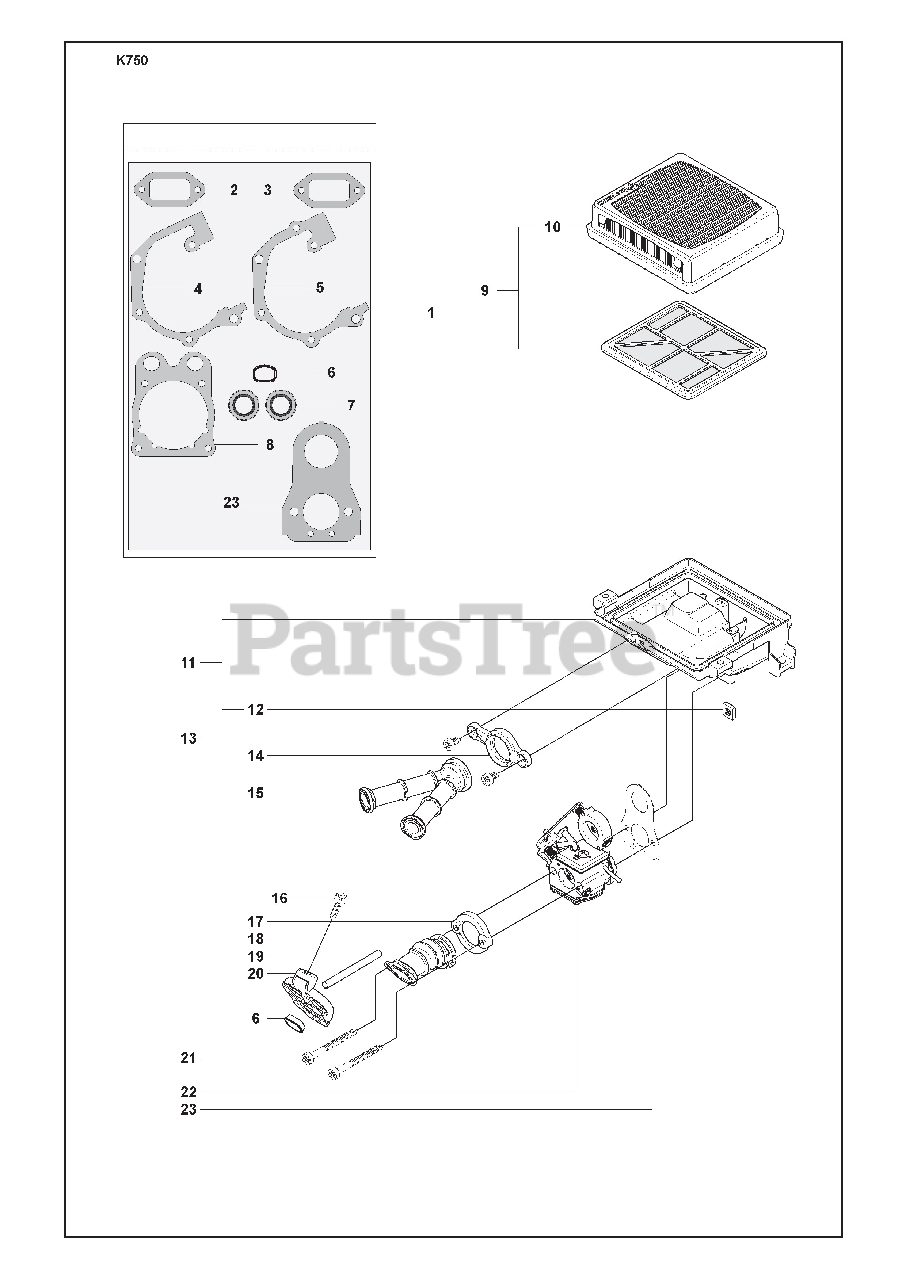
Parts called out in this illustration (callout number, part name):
1	GASKET KIT
3	GASKET
7	SEALING RING
9	FILTER
10	AIR FILTER PAPER
11	CARBRETOR BRACKET
15	RP INLET PIPE
17	FLANGE
18	RP INLET PIPE
19	RP HOSE
20	PLATE, INLET ASSY
22	CARBURETOR
23	RP GASKET CARBURETOR
